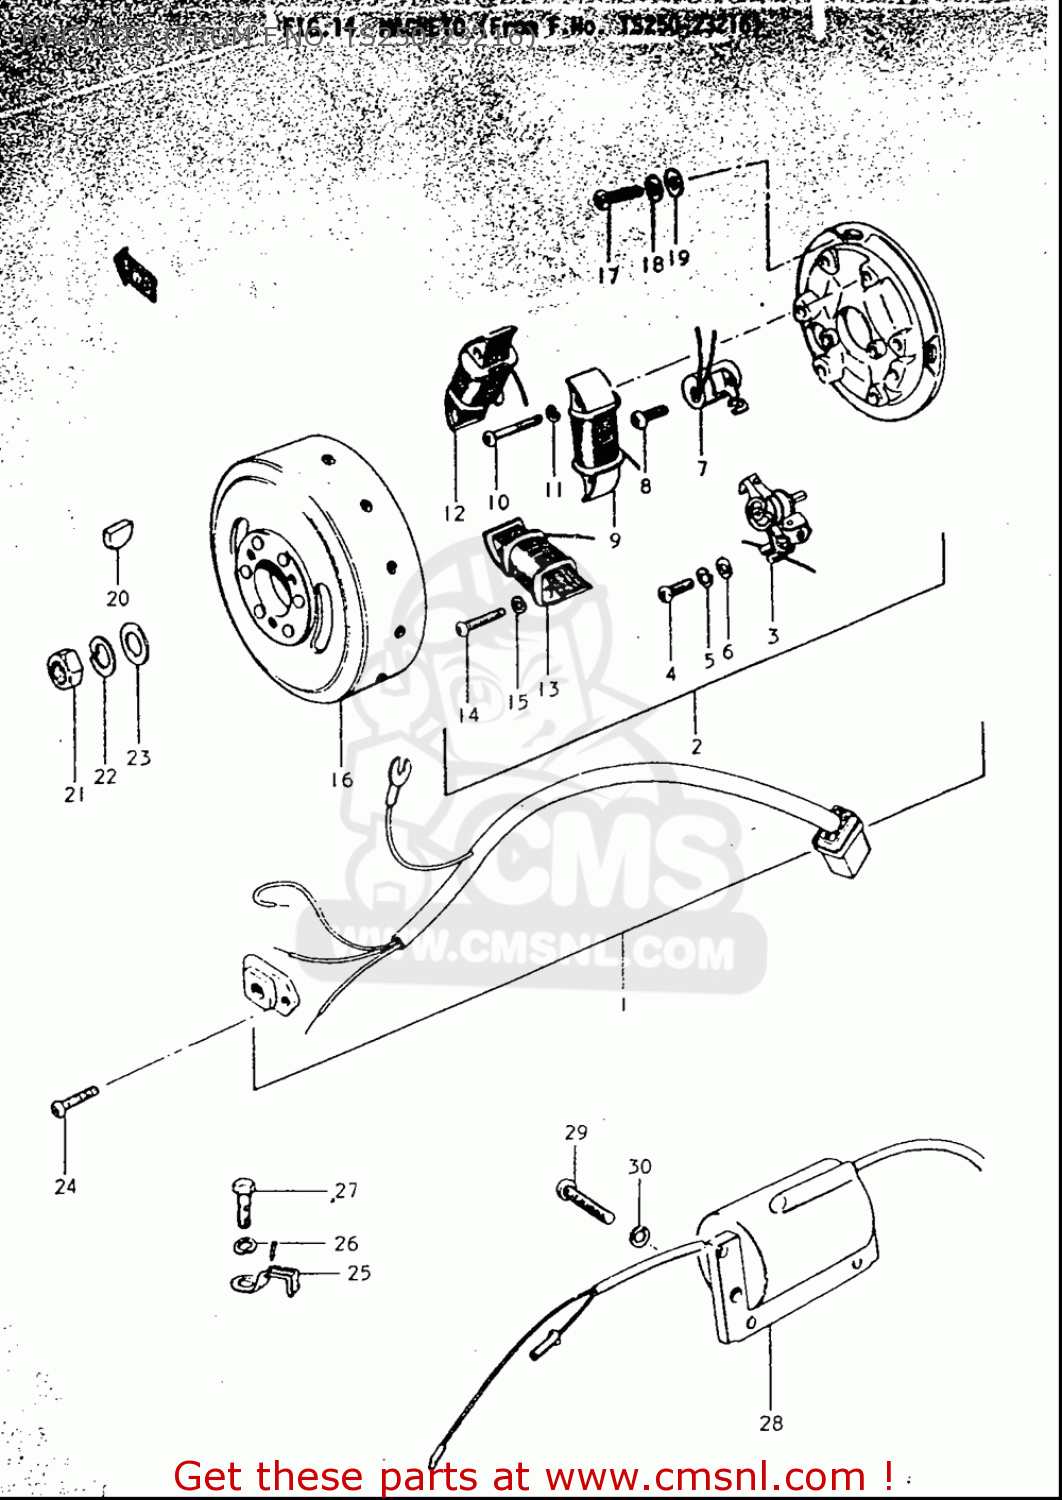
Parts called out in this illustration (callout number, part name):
3	POINT ASSY,CONTACT
4	.SCREW
5	WASHER,LOCK
6	WASHER
7	CONDENSER
11	WASHER,LOCK
15	WASHER,LOCK
17	SCREW
18	WASHER,LOCK
19	WASHER
20	KEY
21	NUT
22	WASHER,LOCK
23	WASHER(14X27X3)
26	WASHER,LOCK
30	WASHER,LOCK
